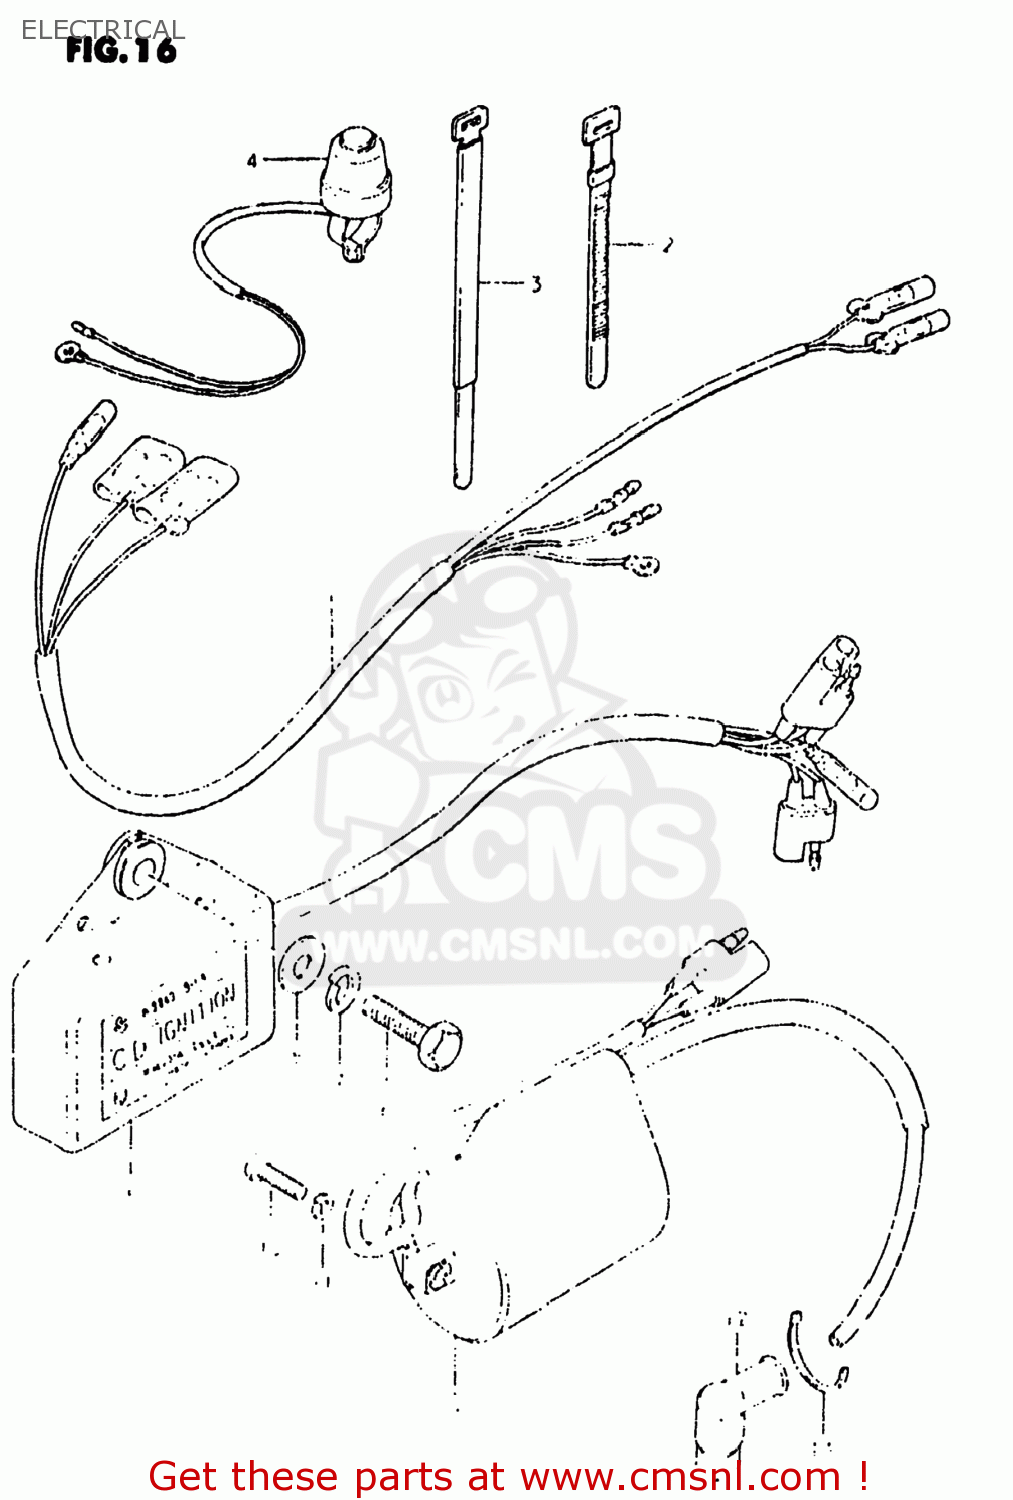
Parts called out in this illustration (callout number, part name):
1	HARNESS,WIRING
2	CLAMP(L:120)
3	CLAMP
4	SWITCH ASSEMBLY
5	CDI UNIT
6	BOLT
7	LOCK WASHER
8	WASHER(6.5X16X1.2)
9	COIL ASSEMBLY,IGNITION
10	SCREW 5X20
11	LOCK WASHER
12	CAP,SPARK PLUG
13	CLAMP
